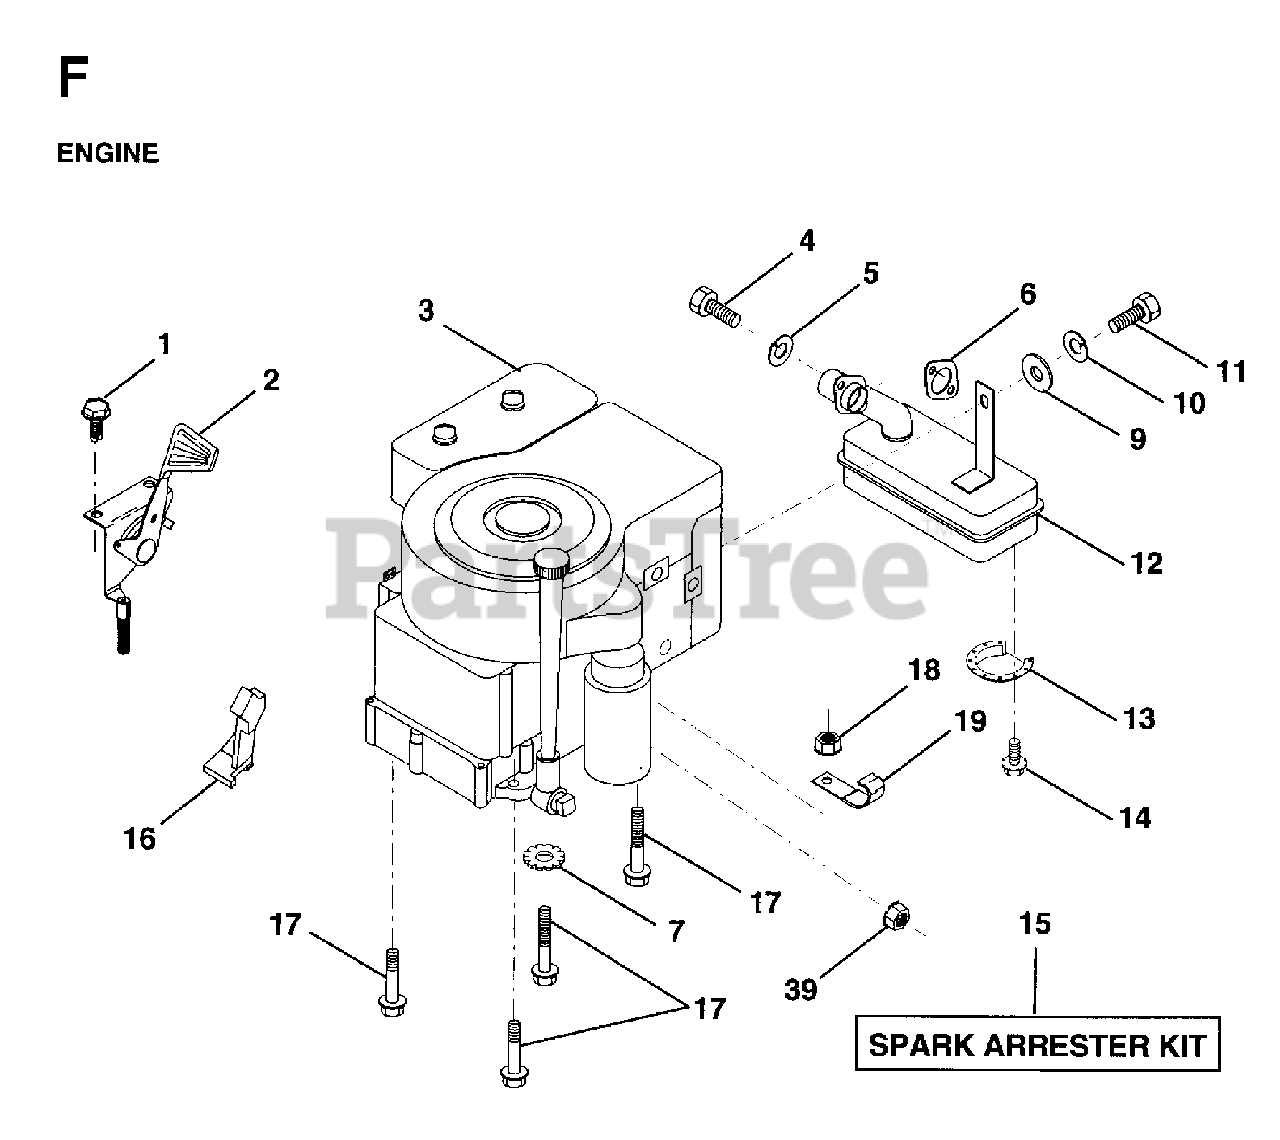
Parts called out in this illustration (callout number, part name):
2	THROTTLE CONTROL
4	SCREW
6	GASKET ENG
7	LOCKWASHER
9	WASHER
10	LOCKWASHER
13	DEFL MUFFLER LTV
14	SCREW
15	ARRESTER SPARK (OPTIONAL)
16	STOP THROTTLE
17	SCREW LT
19	CLIP T
39	NUT FLANGE 1/4-20 STARTER NUT
S	LOCKWASHER
